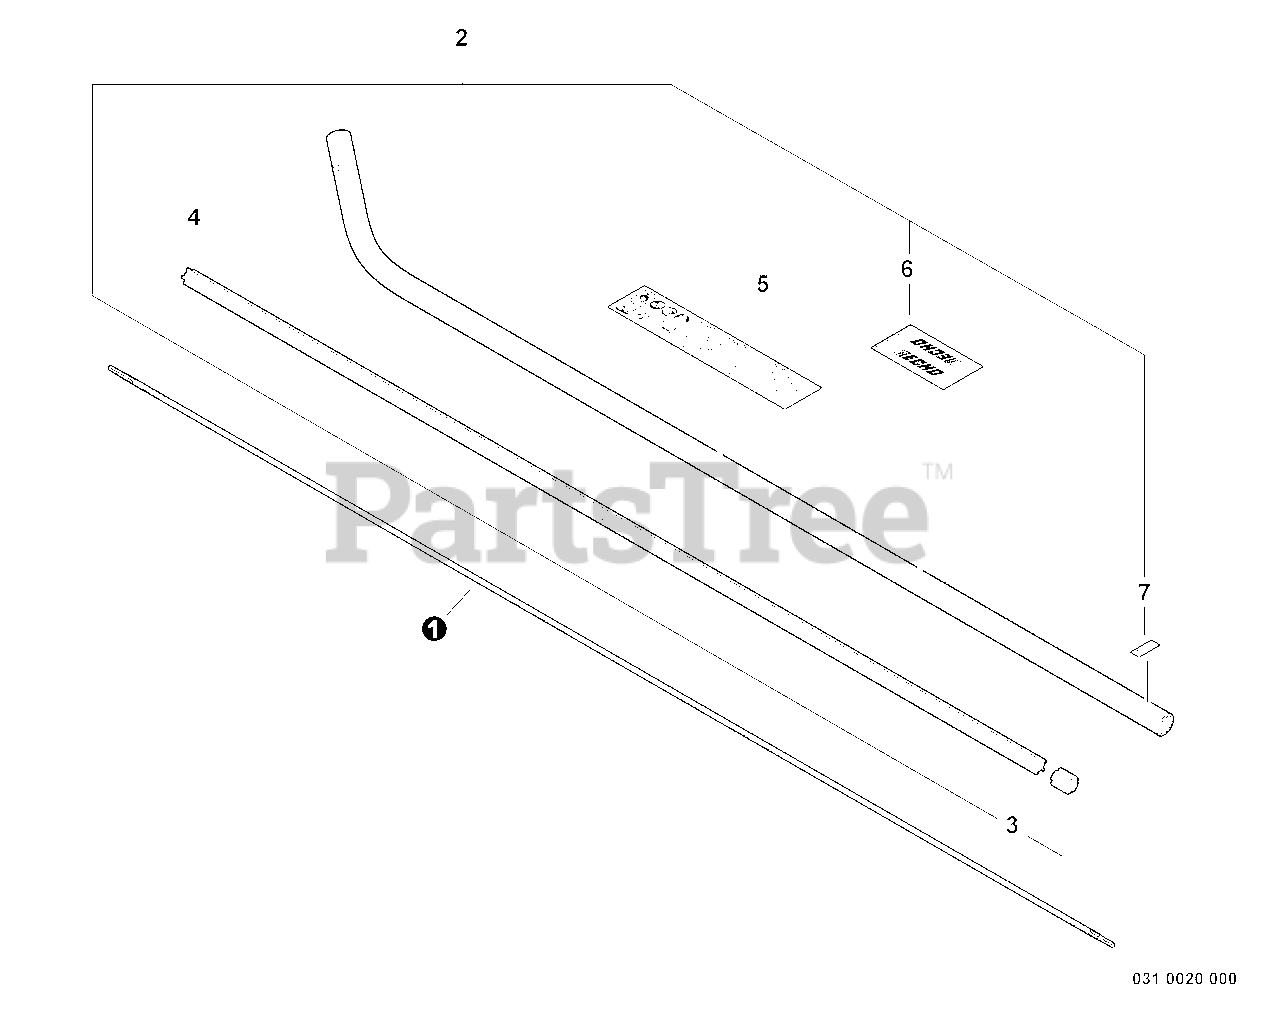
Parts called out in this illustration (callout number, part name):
1	DRIVESHAFT - FLEXIBLE
2	MAIN PIPE ASSY
4	LINER - FLEXIBLE
5	LABEL - CAUTION
6	LABEL - HANDLE LOCATION
7	LABEL - ALIGNMENT
